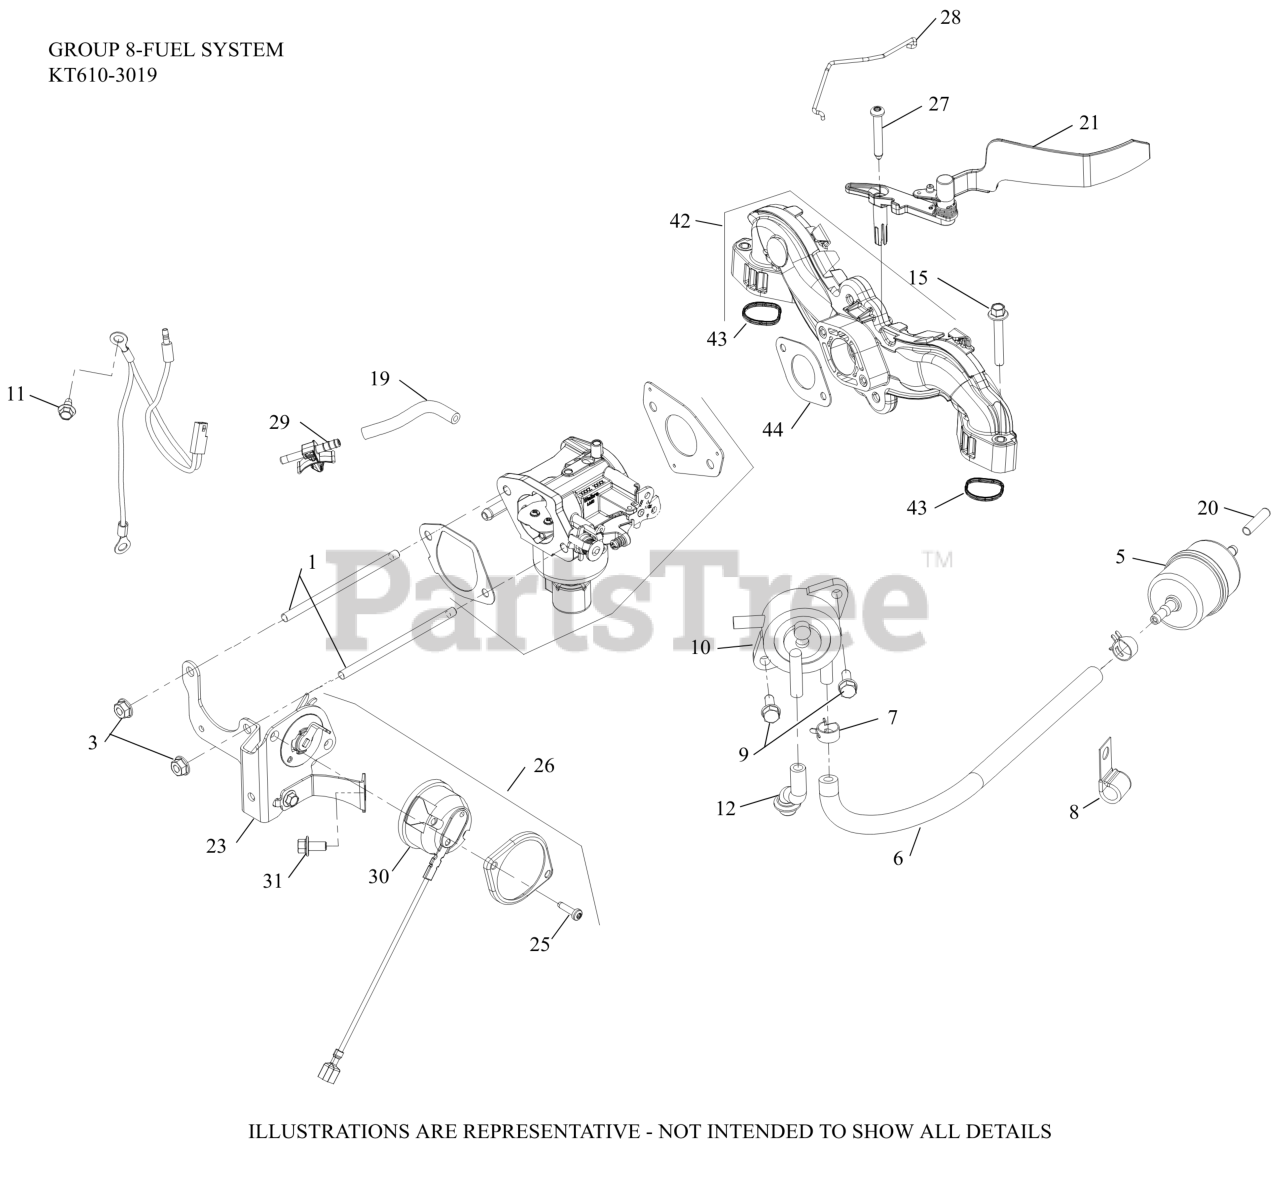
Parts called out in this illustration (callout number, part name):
3	NUT, FLG M6X1.0
5	FILTER, FUEL
6	HOSE,LW PERM.FUEL 24.00"-USE 25 111 81-S
7	SPRING CLAMP, HOSE
8	CLIP, CABLE (KM)
9	SCREW, TAP M6X1.7X18
10	PUMP, FUEL (PULSE)-(#2539326S)
11	SCREW, THREAD FORMING
12	HOSE, PULSE PUMP(STEEL COVERS)
15	SCREW, FLG M6X1.0X40
19	HOSE EVAPORATIVE (WALBRO)
20	CAP, MASKING
21	DEFLECTOR ASSEMBLY, AIR VANE
23	BRACKET ASSY, AUTO-CHOKE (MECH)
25	SCREW, PAN HEAD THREAD FORMING (M4)
26	THERMOSTAT ASSY (CDI) - USE 32 755 27-S
26	THERMOSTAT ASSY(MDI IGN)-USE 32 755 27-S
28	LINKAGE, CHOKE UPLOADER
29	CONNECTOR, EVAPORATIVE
30	KIT, THERMOSTAT, ELECTRIC CHOKE
31	SCREW, FLG M6X1.0X12
42	INTAKE MANIFOLD W/GASKETS
43	O-RING, INTAKE PORT
44	GASKET, CARBURETOR (PIM, CV)
NI	KIT, HIGH ALT (19MM) NIKKI G-TYPE TWIN
NI	KIT, OVERHAUL NIKKI G-TYPE TWIN
NI	KIT, BOWL WITH O-RINGS NIKKI G-TYPE TWIN
NI	KIT, FLOAT AND NEEDLE NIKKI G-TYPE TWIN
NI	KIT,CHOKE REP(SMART/E-CHOKE)-DISC.
NI	KIT,THROTTLE SHAFT(19MM)NIKKI G-TYPETWIN
NI	KIT,CARB (NIKKI)
NI	KIT, O-RING
NI	KIT, SOLENOID (NIKKI)
